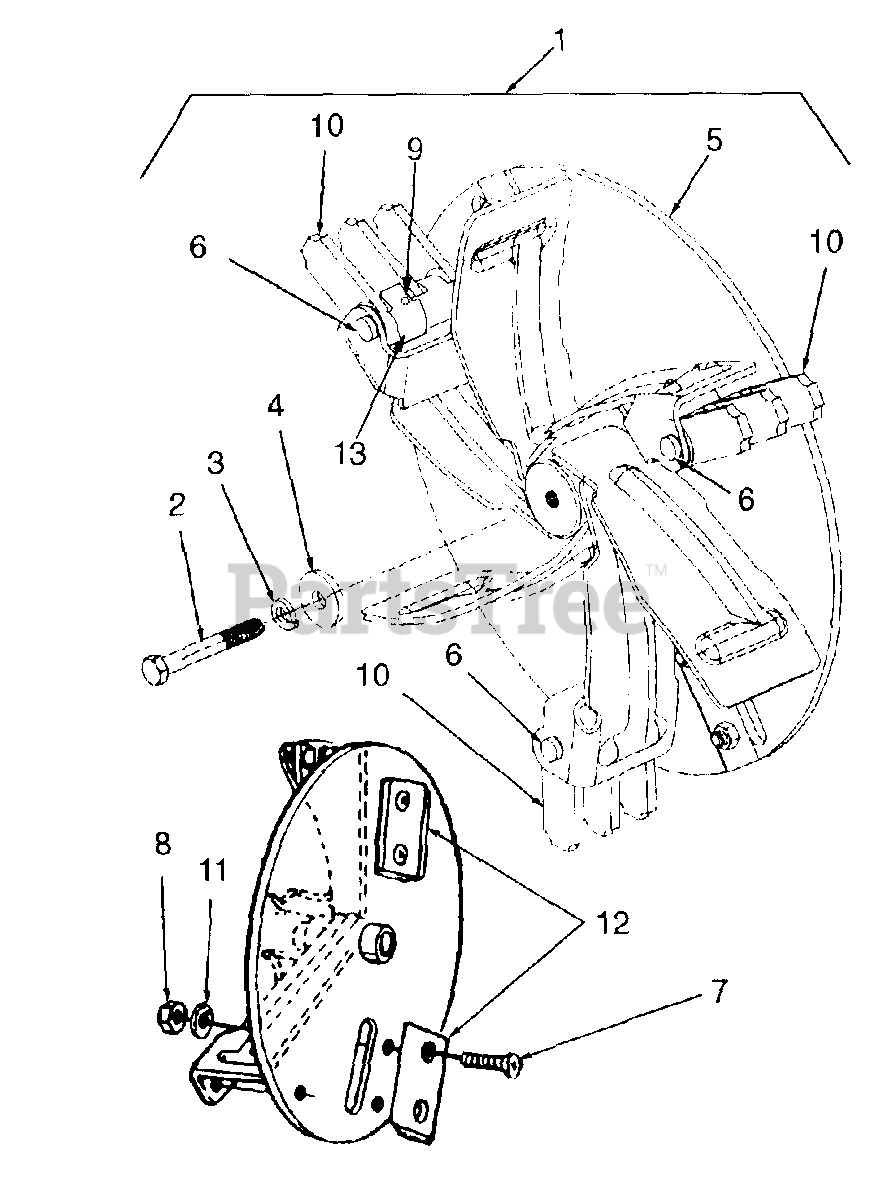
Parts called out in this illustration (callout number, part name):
1	Impeller Ass'y, Complete (CVS24)
2	Screw, Hex Cap, 3/8-24 x 2.75 GR5
3	Washer, Lock, 3/8 Heavy Duty
4	Washer, Flat, .406 x 1-1/4 HD
5	Impeller Assembly (CVS24)
6	Pin, Clevis
7	Screw, Flat Hd. Cap, 5/16-24 x 1.0
8	Nut, Hex Insert Lock, 5/16-24
9	Pin, Spirol, .156 x 1.000 Std.
10	Blade, Flail
11	Washer, Lock, 5/16
12	Blade, Chipper
13	Clip, Retainer
